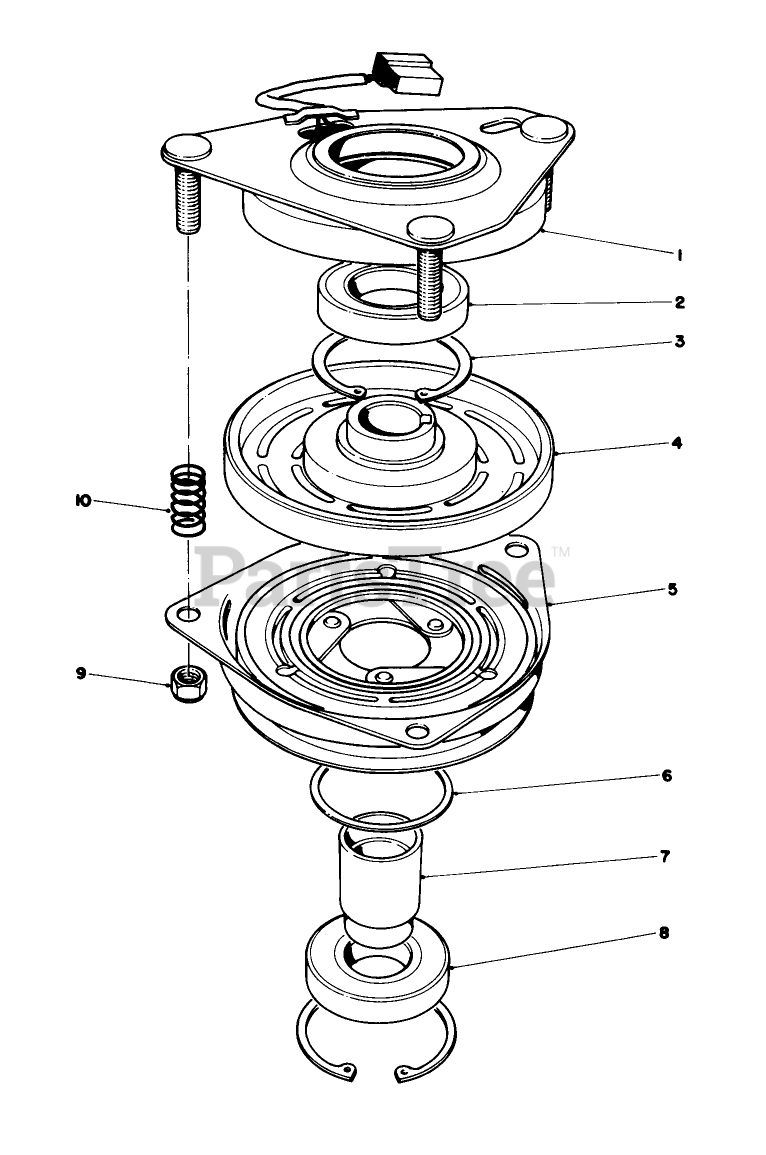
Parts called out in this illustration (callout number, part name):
1	FIELD BEARING ASM
2	BEARING-FIELD
3	RING-RETAINING
4	FIELD COIL/ROTOR BEARING ASM
6	SPACER-BEARING, PULLEY
7	COLLAR-BEARING
9	NUT-LOCK
10	SPRING
